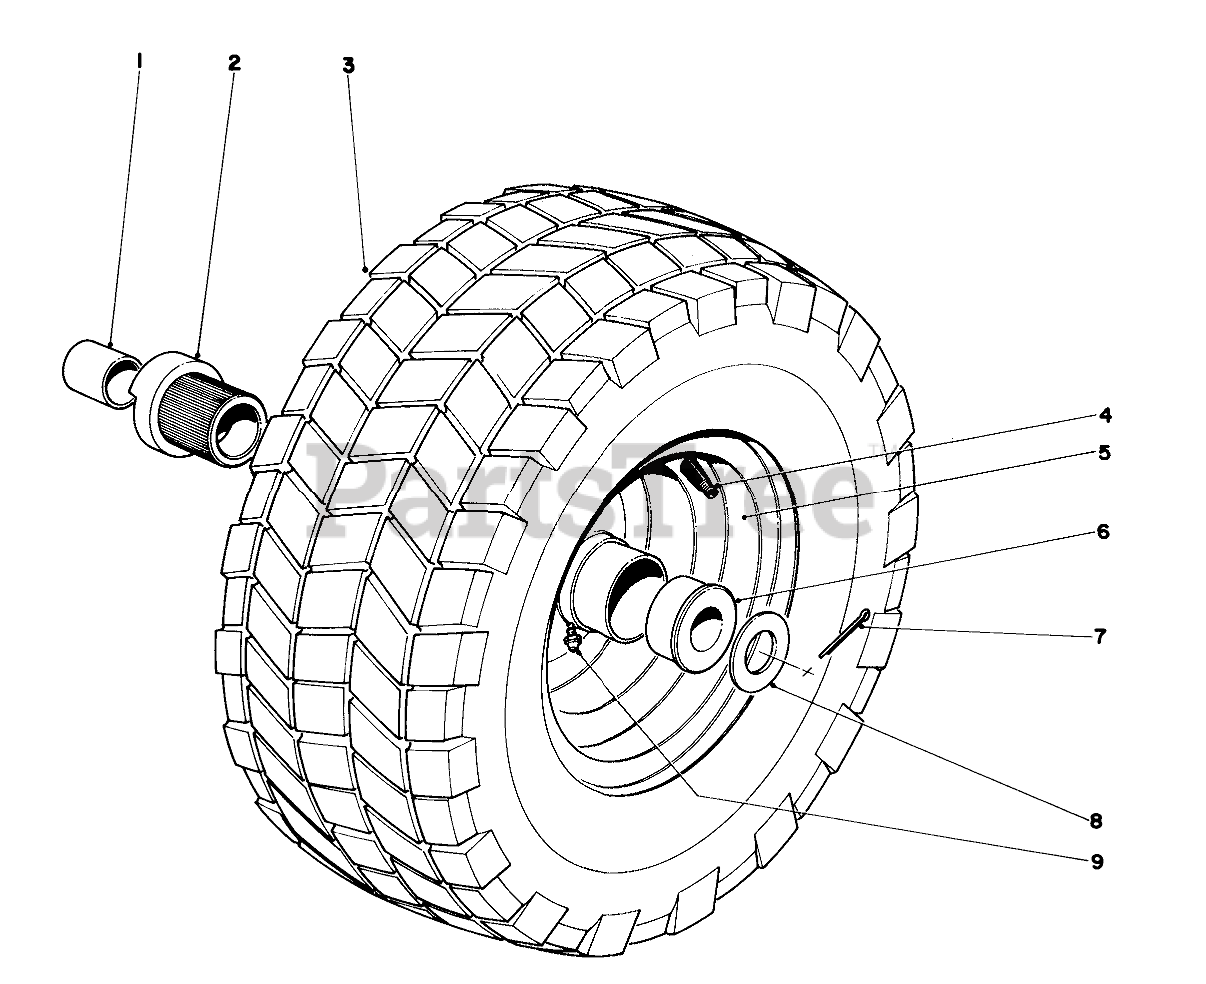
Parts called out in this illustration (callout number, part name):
1	7/8 ID X 1 LG BUSHING
2	Hub Jaw
3	Tire
4	STEM-VALVE
5	Wheel Rim
6	Bushing
7	PIN-COTTER
8	THRUST WASHER
9	FITTING-GREASE
